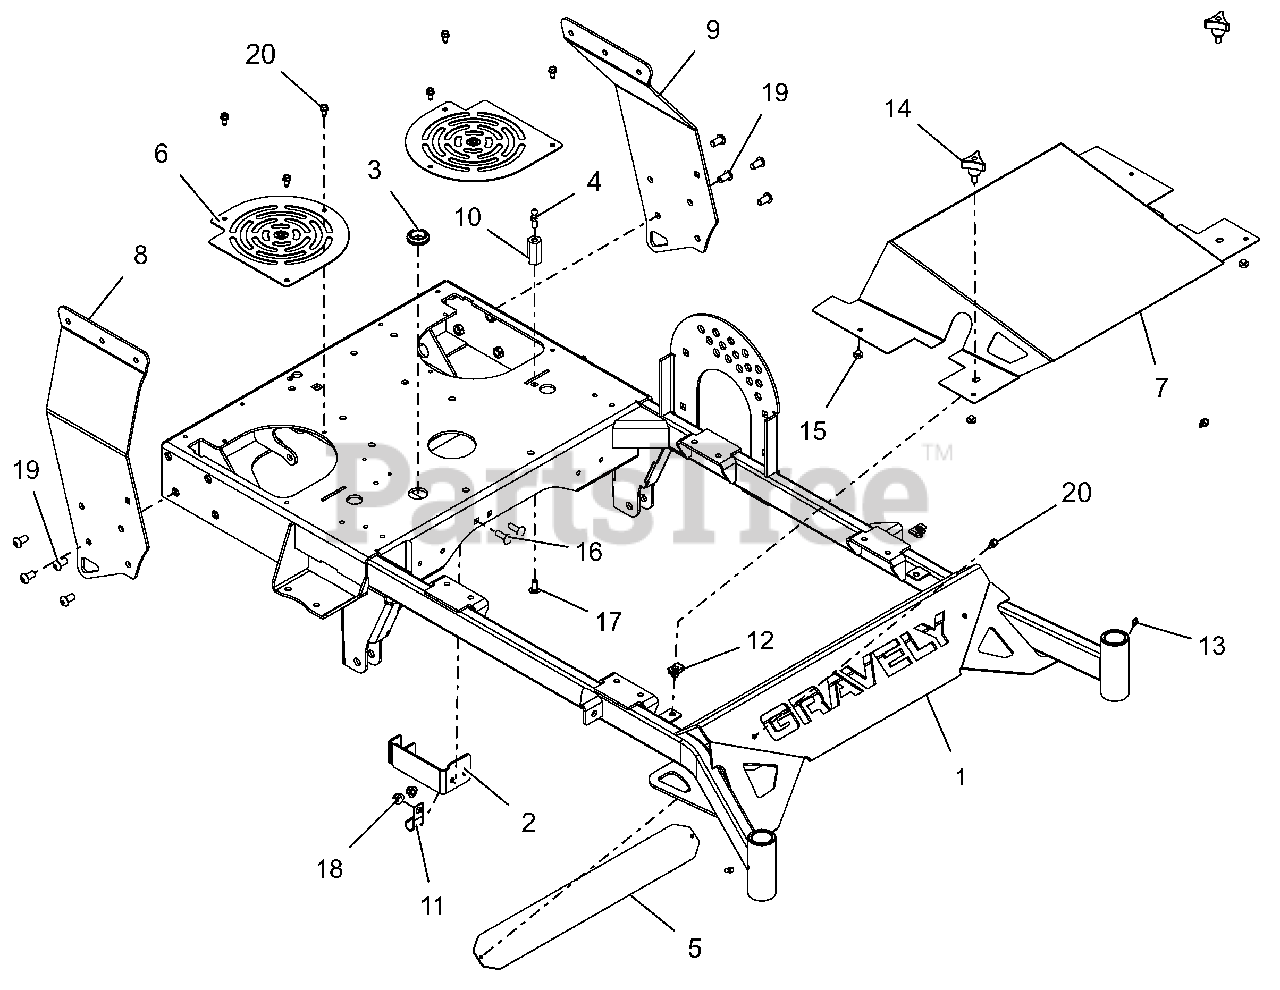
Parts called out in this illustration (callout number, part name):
1	WLDMT, FRAME 48" HYDRO PRO WLK
2	WLDMT, CLUTCH STOP
3	GROMMET:RUB:.88IDX1.38ODX.14GR
4	STUD- BALL
5	BUMPER LOGO BACKING PLATE -BLK
6	COVER, COOLING FAN (RED)
7	KIT, 48" FRONT SHEILD W DECALS
8	PANEL, RH TANK TOWER (RED)
9	PANEL, LH TANK TOWER (RED)
10	SPCR, DAMPENER MTG
12	NUT-CLIP RETAINER 5/16-18X.56
13	FTG-LUBE .25-28X.256 SST
14	KNOB,WING STUD 5/16-18 X .75
15	BUMPER GROMMET
16	@BLT-RHDSSQNK .31-18X1.00 G5YZ
17	@BLT-RHDSSQNK .31-18X.75 G5YZ
18	@NUT-LK-NYL-FLG .31-18 YWZC
19	BLT-BTHD-SOCKET .38-16X.75
20	SCR-TAP .25-20X.50 HWH TR YWZ
